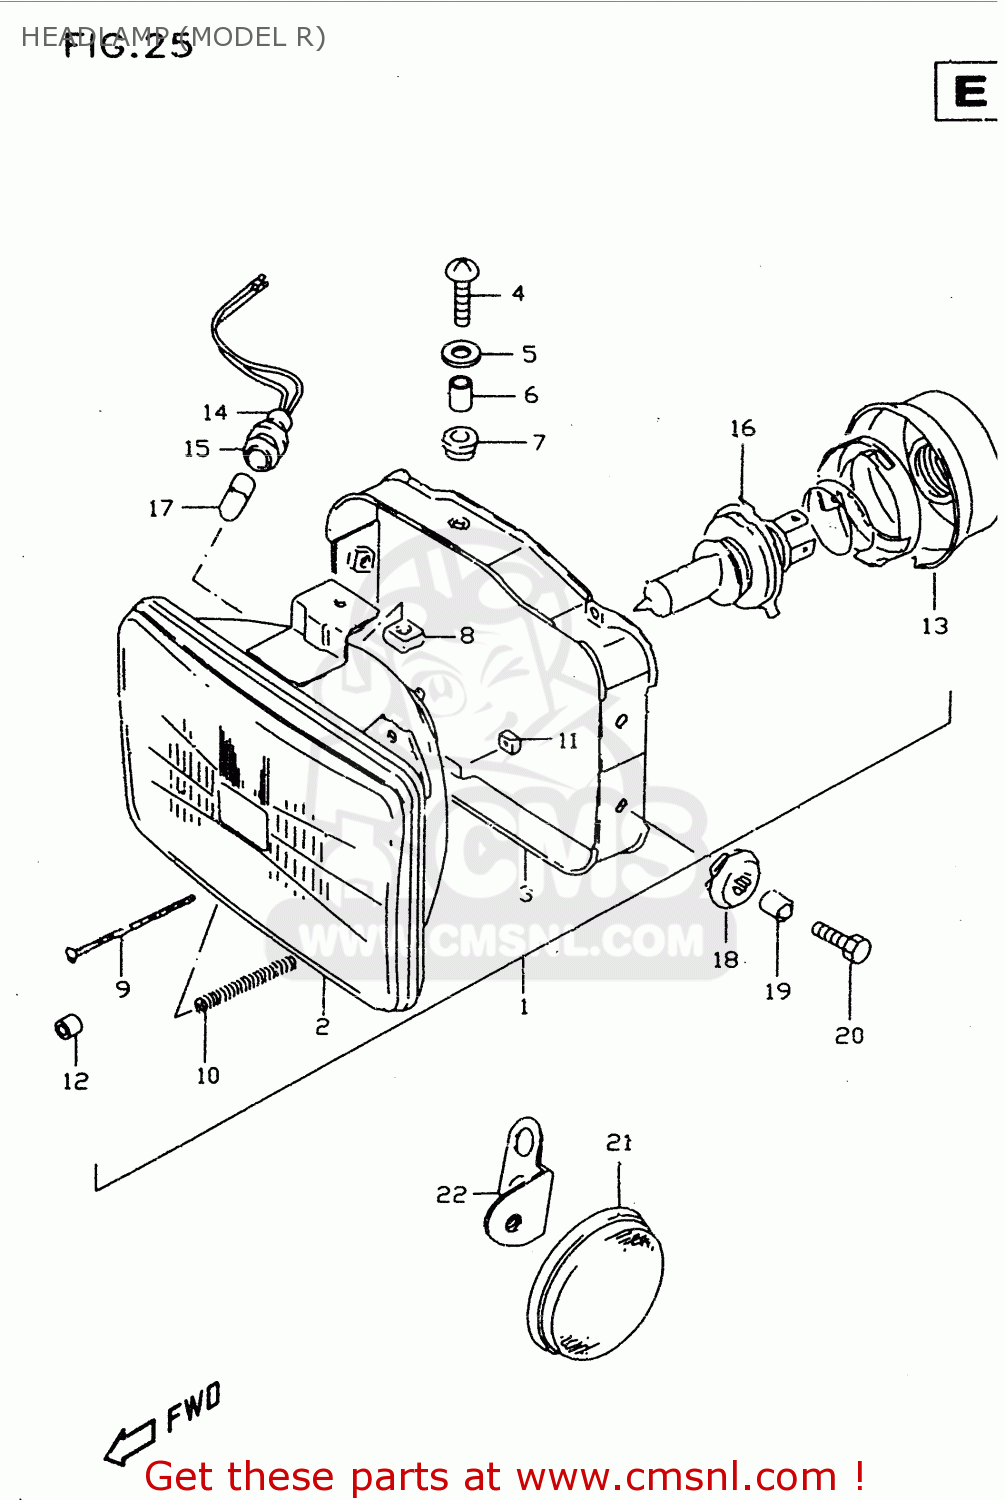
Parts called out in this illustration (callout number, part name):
1	HEADLAMP ASSY
2	LAMP UNIT
3	HOUSING
4	SCREW
5	WASHER (5.5X18X1)
6	SPACER
7	CUSHION
8	NUT
9	SCREW
10	SPRING
11	NUT
12	CAP,SCREW
13	COVER,SOCKET
14	CORD,POSITION
15	JOINT,RUBBER
16	BULB(12V60/55W,H4)
17	BULB(12V4W)
18	CUSHION
19	SPACER(6.3X9.1X11.5)
20	BOLT(6X20)
21	REFLECTOR,REFLEX FR
22	BRACKET,FR SIDE REFLECTOR,L
